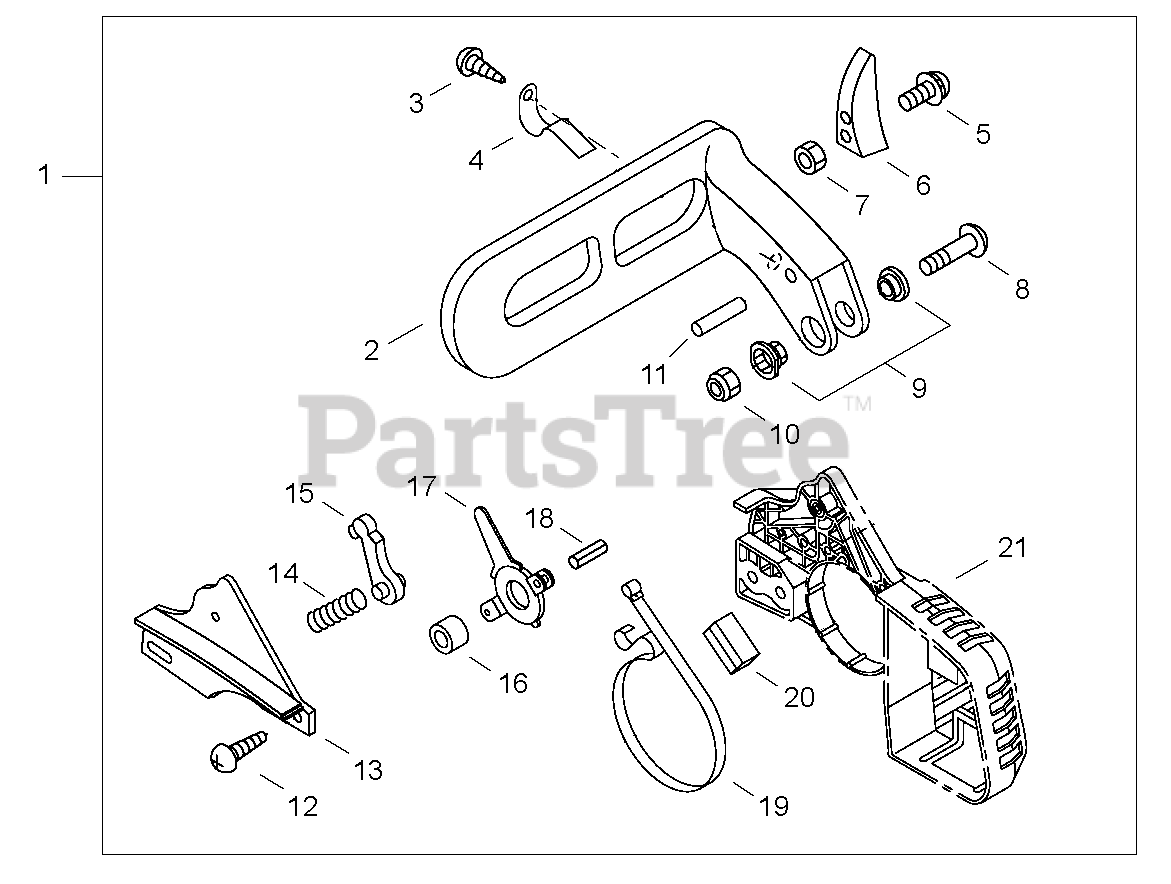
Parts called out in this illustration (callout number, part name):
1	BRAKE ASSY, CHAIN
2	BRAKE, CHAIN
3	SCREW 4×10
4	SPRING, FLAT
5	SCREW 4×20
6	WEIGHT, BRAKE
8	SCREW 5×32
9	COLLAR 5.3×10×13×L5
10	NUT, LOCK M5
11	ROLLER 4×23.8
12	SCREW 4×12
13	COVER, BRAKE
14	SPRING, COMPRESSION
15	STOPPER, BRAKE
16	SPACER 8×12×9
17	LEVER, BRAKE
18	PIN, SPRING 4×8.8
19	BAND, BRAKE
20	SEAL, BRAKE
21	GUARD, SPROCKET
